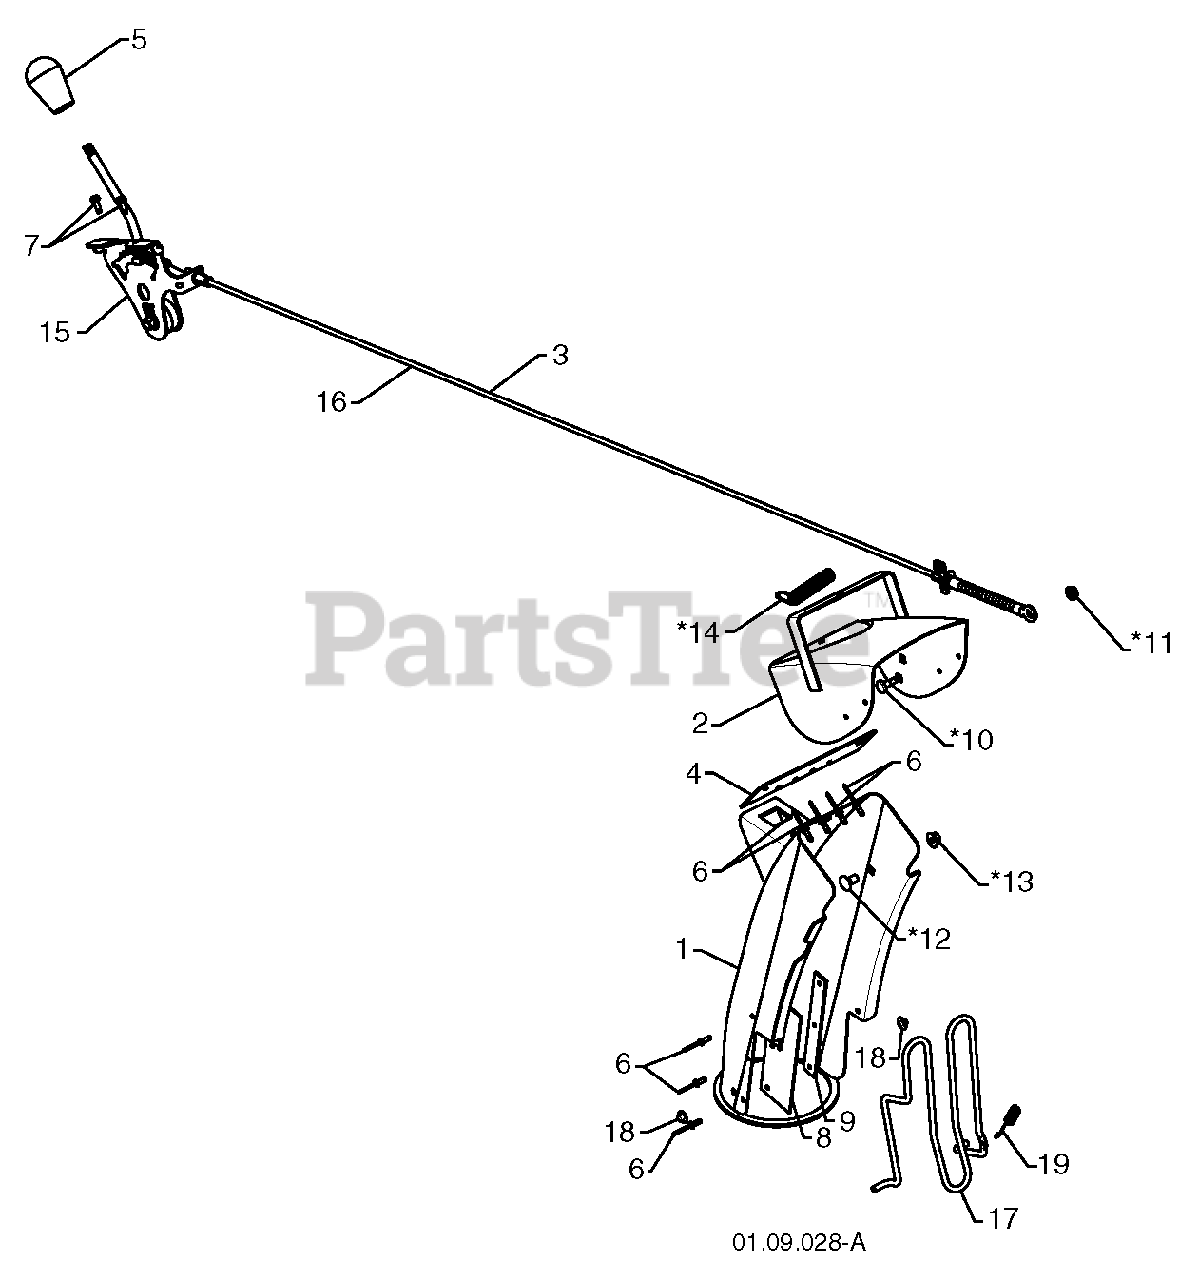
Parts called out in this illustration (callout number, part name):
3	CONTROL.ASM.DEFLECTOR
4	SEAL.DEFLECTOR
5	KNOB LEVER, BLACK
6	RIVET BLIND
7	SCREW #10-24 X 5/8
8	SHIELD.SNOW.CHUTE
10	BOLT, SHOULDER
11	NUT.HEX.FLANGE.1/4
12	BOLT
13	NUT, LOCK 5/16-18
15	CHUTE.DEFLECTOR.HEAD.SERVICE.
16	SERVICE.CHUTE.DEF.CBL.BLK
